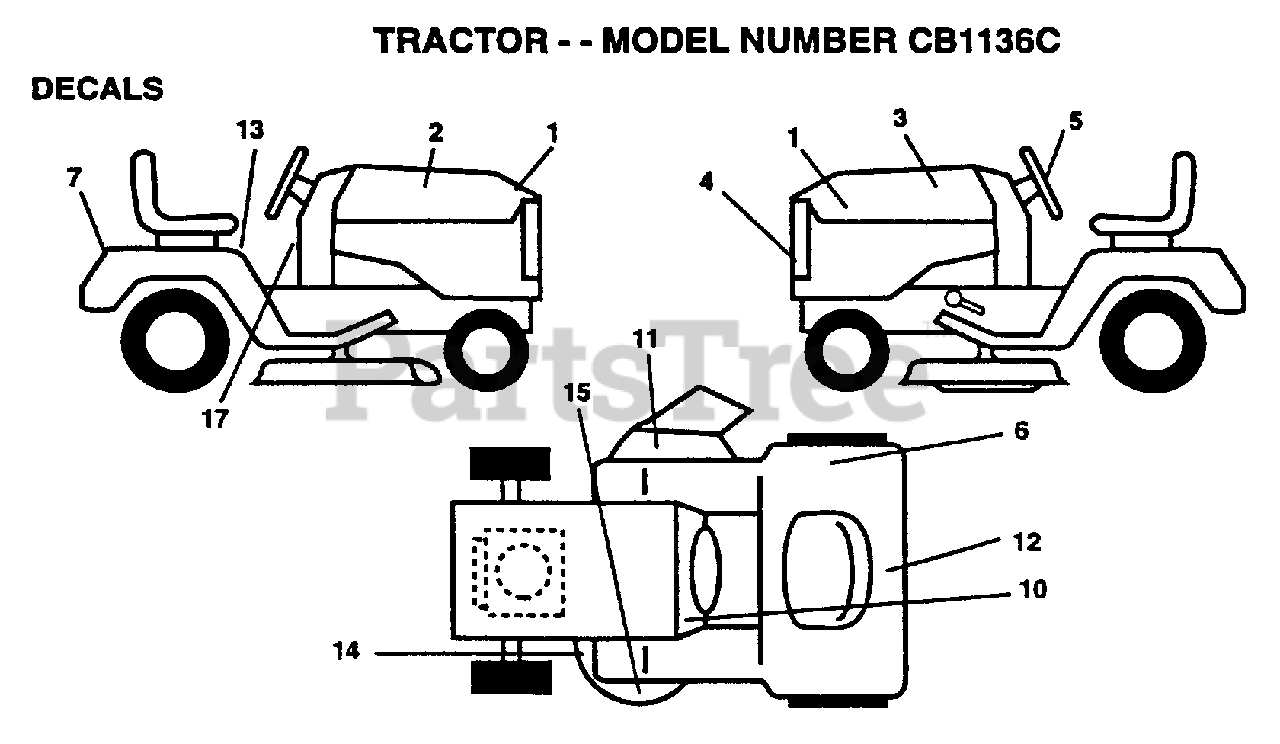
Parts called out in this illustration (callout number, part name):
1	DECAL.ONL.SIDE
2	DECAL.HD.RH.COOP
3	DECAL.HD.LH.COOP
4	DECAL.GRILLE.COOP
5	DECAL.INS.WHL.STG
7	DECAL.FEND.COOPER
10	DECAL.OP.INST.SYM
11	DECAL.DANGER.CUTF
12	DECAL.BATRY.3-3908
13	DECAL.READ.O.MANU
14	DECAL.V.BELT
17	DECAL.EURO.ST.CE.
